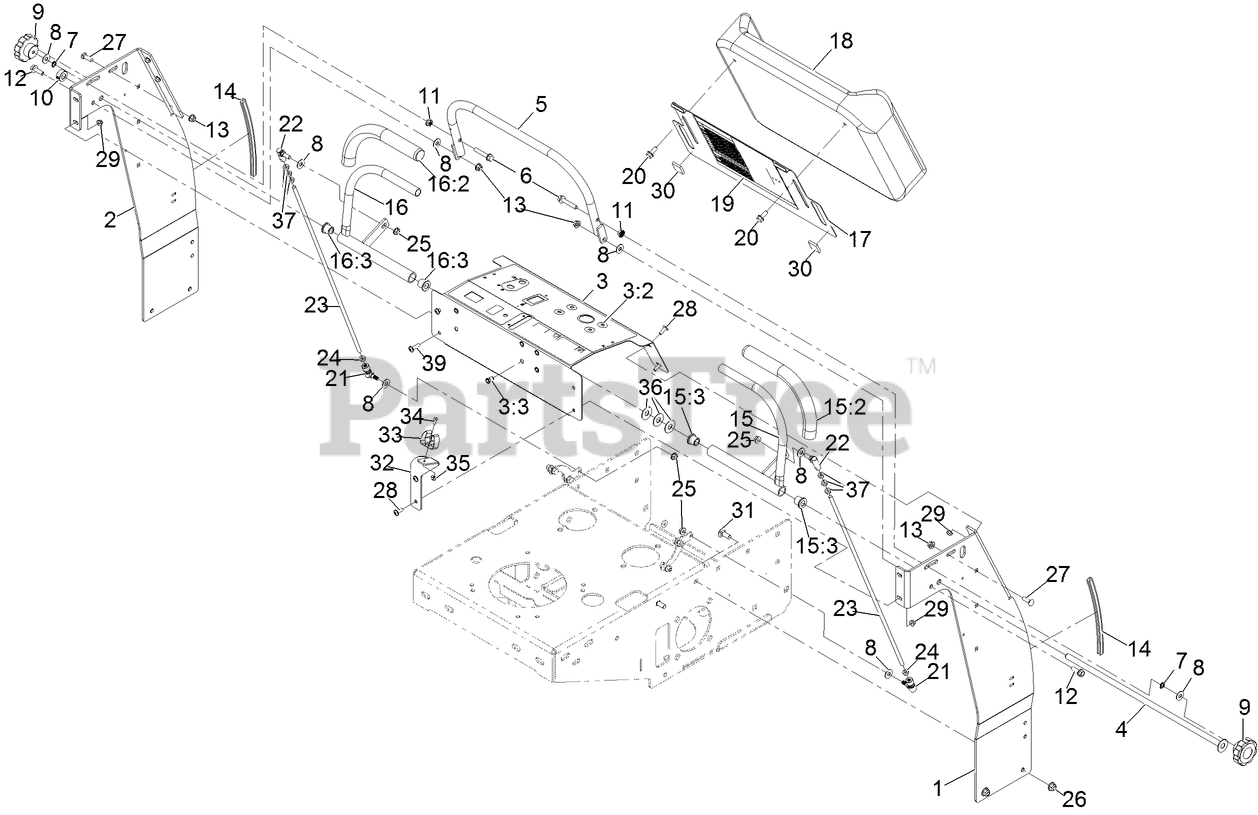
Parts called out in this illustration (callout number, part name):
1	UPRIGHT-LH, JR36 [BLK-TXT]
2	UPRIGHT-RH, JR36 [BLK-TXT]
3	ASM-PANEL, CONTROL
3:2	DECAL-CONTROL
3:3	NUT-CLINCH, HEX
4	ROD-PIVOT, JOY STICK
5	BAR-SPEED [BLK-TXT]
6	SCREW-HHF
7	WASHER-LOCK
8	FLAT WASHER, 5/16 NOM,ST/ST,18-8
9	KNOB-FLUTED
10	COLLAR
11	NUT-HEX FLANGE
12	SCREW-HHF
13	NUT-HEX FLANGE
14	STRIP-TRIM, 9.0"
15	STICK-JOY, LT
15:2	GRIP-CONTROL, MOTION
15:3	BUSHING-FLANGE
16	STICK-JOY, RT
16:2	GRIP-CONTROL, MOTION
16:3	BUSHING-FLANGE
17	PLATE, KNEE PAD, JR36
18	PAD-KNEE
19	DECAL-CHART, SPRAY
20	SCREW-HHF
21	BALL JOINT-QUICK DISCONNECT, SS
22	BALLJOINT-SS
23	LINKAGE-CONTROL, SS
24	NUT-HEX
25	NUT-HHF
26	NUT-HEX FLANGE
27	BOLT,CARRIAGE,5/16-18X1,ST/ST 18-8
28	SCREW-HSBHF
29	NUT-HEX FLANGE
30	VELCRO
31	SCREW-CARR
32	MOUNT, GUN, JR36
33	HOLDER-TOOL, CLIP
34	SCREW-HSBH
35	NUT-HEX FLANGE
36	WASHER
37	NUT-HEX
39	SCREW-HSBHF
